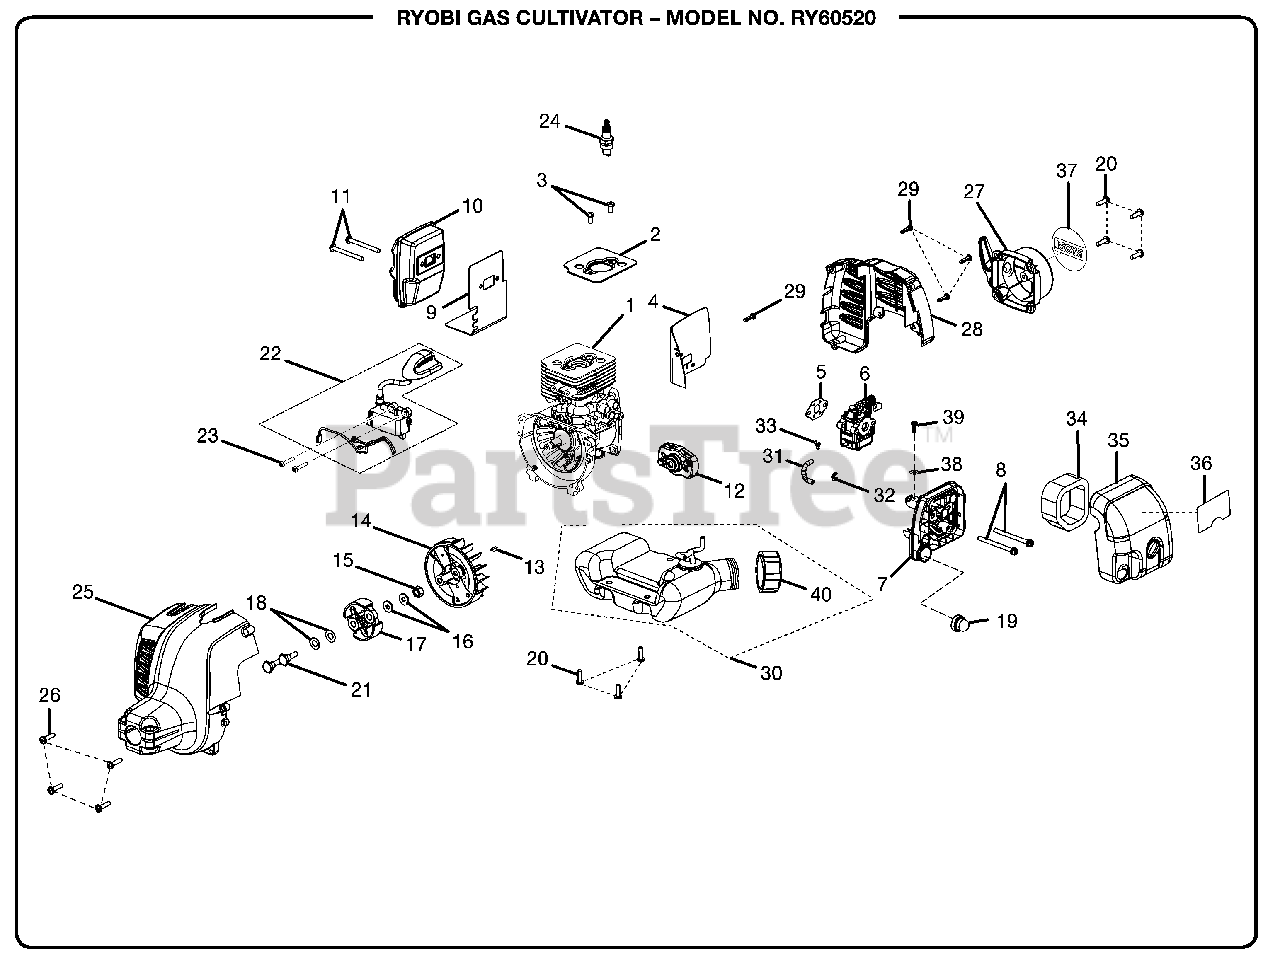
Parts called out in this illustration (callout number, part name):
1	SHORT BLOCK
3	SCREW (M5 x 10 mm PAN HD.)
6	CARBURETOR ASSEMBLY
7	FILTER HOUSING ASSEMBLY
8	SCREW (M5 x 60 mm PAN HD.)
9	GASKET
10	MUFFLER ASSEMBLY
11	SCREW (M5 x 50 mm PAN HD.)
12	PULLEY ASSEMBLY
13	WOODRUFF KEY
14	ROTOR
15	ROTOR NUT
16	WASHER
17	CLUTCH ASSEMBLY
18	CURVED WASHER
19	PRIMER
20	SCREW (M5 X 16 mm)
21	SCREW (M6 x 14 mm PAN HD.)
22	COIL ASSEMBLY
23	SCREW (M4 x 22 mm PAN HD.)
24	SPARK PLUG
25	FRONT HOUSING ASSEMBLY
26	SCREW (M5 x 20 mm PAN HD.)
27	STARTER HOUSING ASSEMBLY
28	REAR ENGINE HOUSING
29	SCREW (M4 x 16 mm PAN HD.)
30	FUEL TANK
31	FUEL LINE
32	HOSE CLIP
33	CLIP
34	AIR FILTER
35	OUTER COVER ASSEMBLY
36	PRIMER LABEL
37	LOGO LABEL
39	SCREW (M4 X 16 mm TORX PAN HD.)
